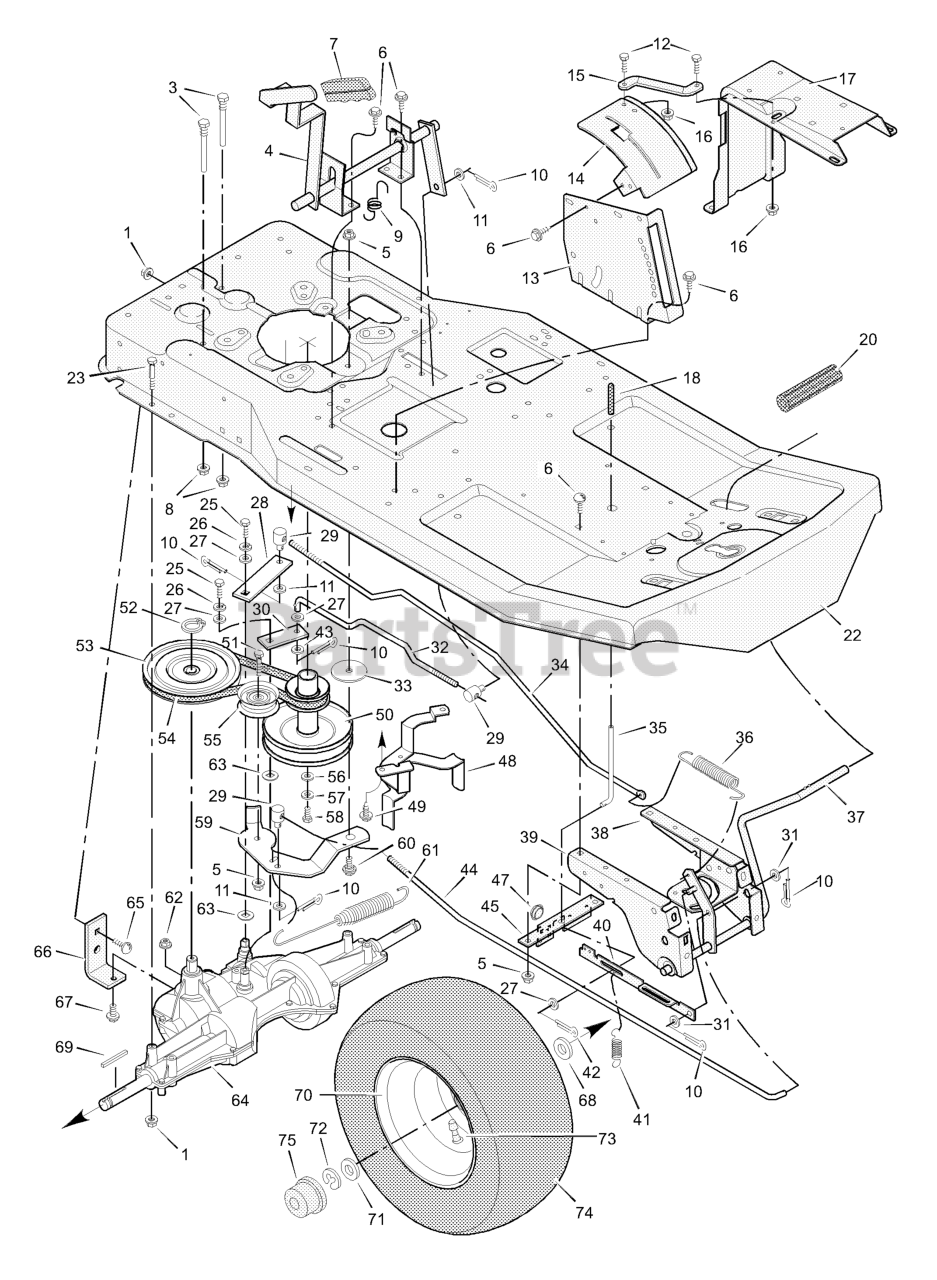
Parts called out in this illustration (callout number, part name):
1	Locknut, Flange
3	GUIDE, Belt
4	Shifter Assembly
5	Locknut, Flange
7	GRIP, Shift Lever
8	Hex Nut
9	SPRING, Extension
10	PIN, Cotter
12	BOLT, Hex
13	Plate, Index
14	Gate, Shift
15	BRACE, Shift Gate
16	Locknut, Flange
17	SUPPORT, Seat
18	GRIP, Parking Brake
22	FRAME Assembly
23	BOLT, Hex
25	BOLT, Hex
26	LOCKWASHER
28	Yoke, Brake
29	NUT, Adjusting
30	Yoke, Shift
32	ROD, Shift
33	WASHER, Hardened
34	ROD, Brake
35	ROD, Parking Brake
36	SPRING, Extension
37	LEVER, Pedal
38	Plate, Left Suspension
39	Plate, Right Suspension
40	Link, Parking Brake
41	SPRING, Extension
42	PIN, Cotter
44	ROD, Clutch
45	Stop, Parking Brake
47	Grommet
48	GUIDE, Belt
50	PULLEY Assembly, Stack
51	BOLT, Hex
52	Ring, Retainer
53	PULLEY, Drive
54	BELT, Motion Drive
55	PULLEY, Idler
57	LOCKWASHER
58	BOLT, Hex
59	BRACKET, Idler
60	BOLT, Shoulder
61	SPRING, Extension
62	Locknut, Hex
65	BOLT, Carriage
66	BRACKET, Transaxle
67	BOLT, Hex
69	Key, Square
70	WHEEL & TIRE ASSEMBLY
72	E-Ring
73	Valve Stem
74	Tire Only
75	Hub Cap
